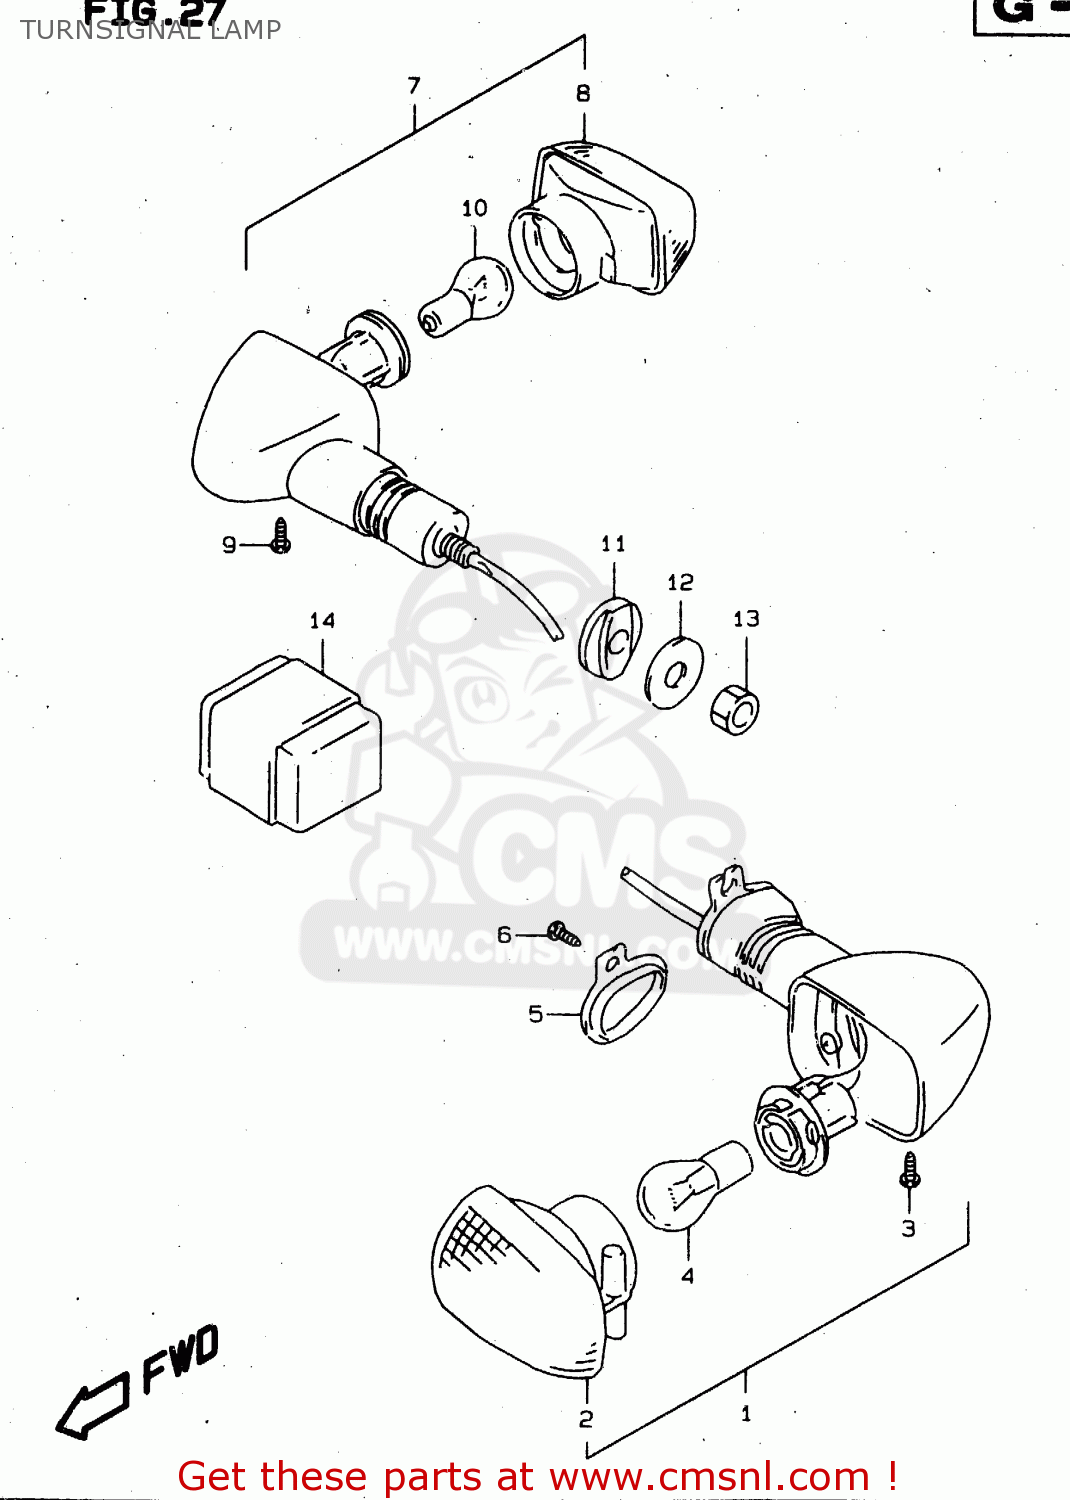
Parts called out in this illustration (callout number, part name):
1	LAMP ASSY,FR TURN SIGNAL,R
2	LAMP UNIT
3	SCREW
4	BULB(12V21W)
5	PLATE,FR TURNSIGNAL LAMP
6	SCREW
7	LAMP ASSY,RR TURNSIGNAL,R
8	LAMP UNIT
9	SCREW
10	BULB(12V21W)
11	SPACER,RR TURNSIGNAL
12	WASHER(10.5X30X2.3)
13	NUT
14	RELAY ASSY
